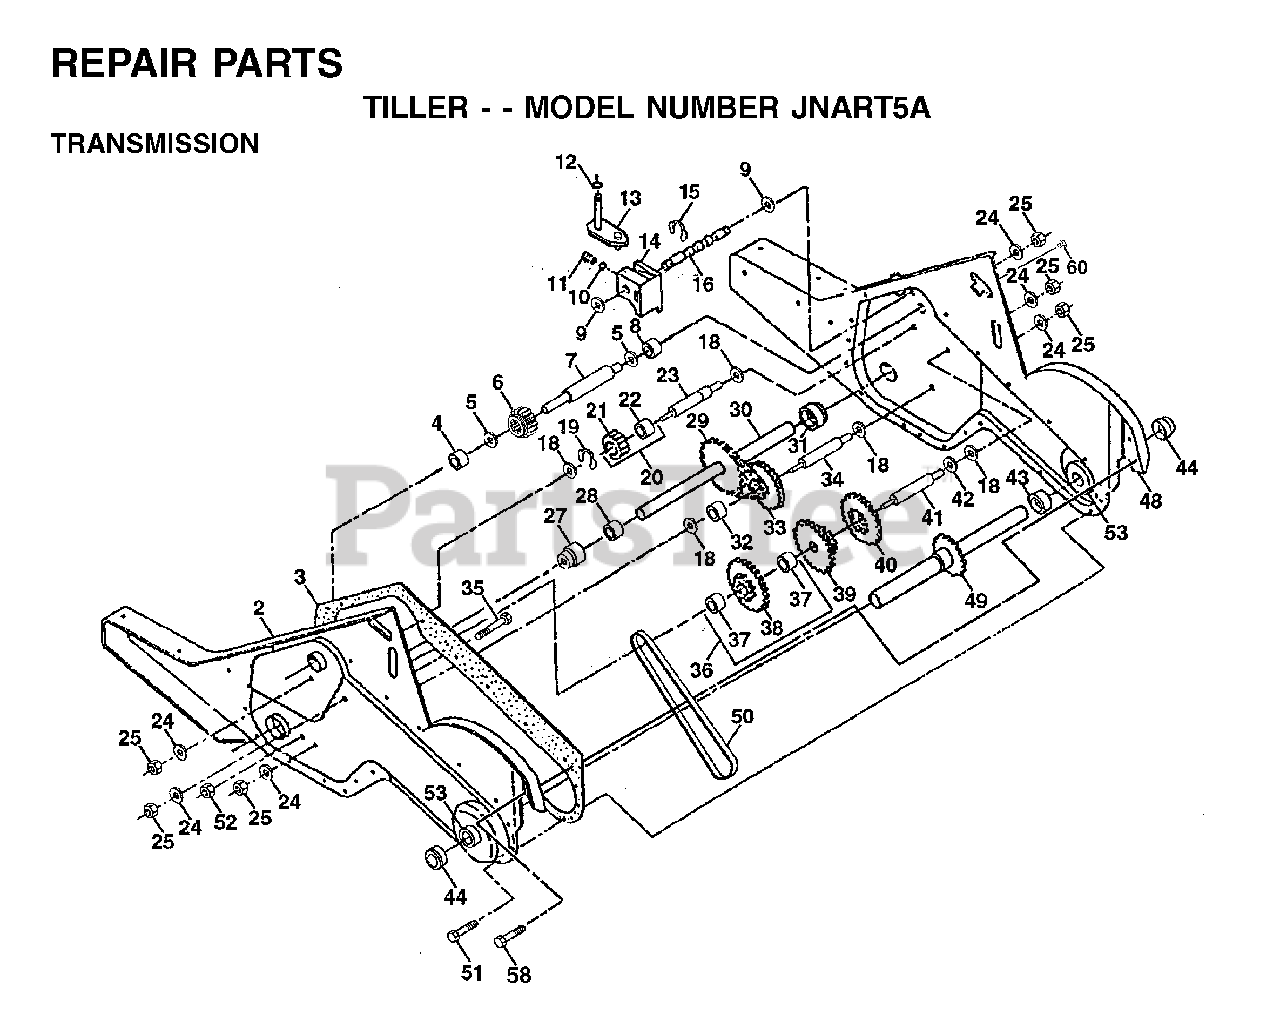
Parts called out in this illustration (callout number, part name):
2	GEARCASE-LH
3	GASKET
4	NEEDLE BRNG LT
5	THRUST WASHER
6	GEAR.PINION.INPUT
7	SHAFT.INPUT."D".TILLER
8	BEARING TI
9	WASHER, SEAL
10	STEEL BALL KIT
11	SPRING-SHIFT CRT
12	O-RING TI
13	SHIFTING ARM
14	SHIFT FORK TI
15	KLIP RING
16	SHAFT.SHIFTER.TILLER
19	KLIP RING
20	GEAR ASSY CRT
21	GEAR-REV IDLR CRT
22	NEEDLE BEARING TI
23	SHAFT CRT
24	LOCKWASHER
27	BEARING, SHAFT LH CRT
29	CHAIN CRT
30	GROUND SHAFT ASS'Y
31	BEARING, SHAFT RH CRT
32	SPACER TI
33	SPRCKT 8 GEAR CRT
34	SHAFT.SECONDARY.REDUCTION.CRT
35	SCRW WHIZ LOK CRT
36	SPROCKET ASS'Y W/BRG
37	BEARING
38	SPROCKET, TINE
39	GEAR TI
41	SHAFT.REDUCTION.TILLER
42	BRNG RACE T
43	SPACER TI
44	SEAL ASM, OIL
48	GEARCASE
49	TINE SHAFT
50	CHAIN.TILLER
51	SCREW
53	BEARING KIT
58	SCREW
60	ZERK M
